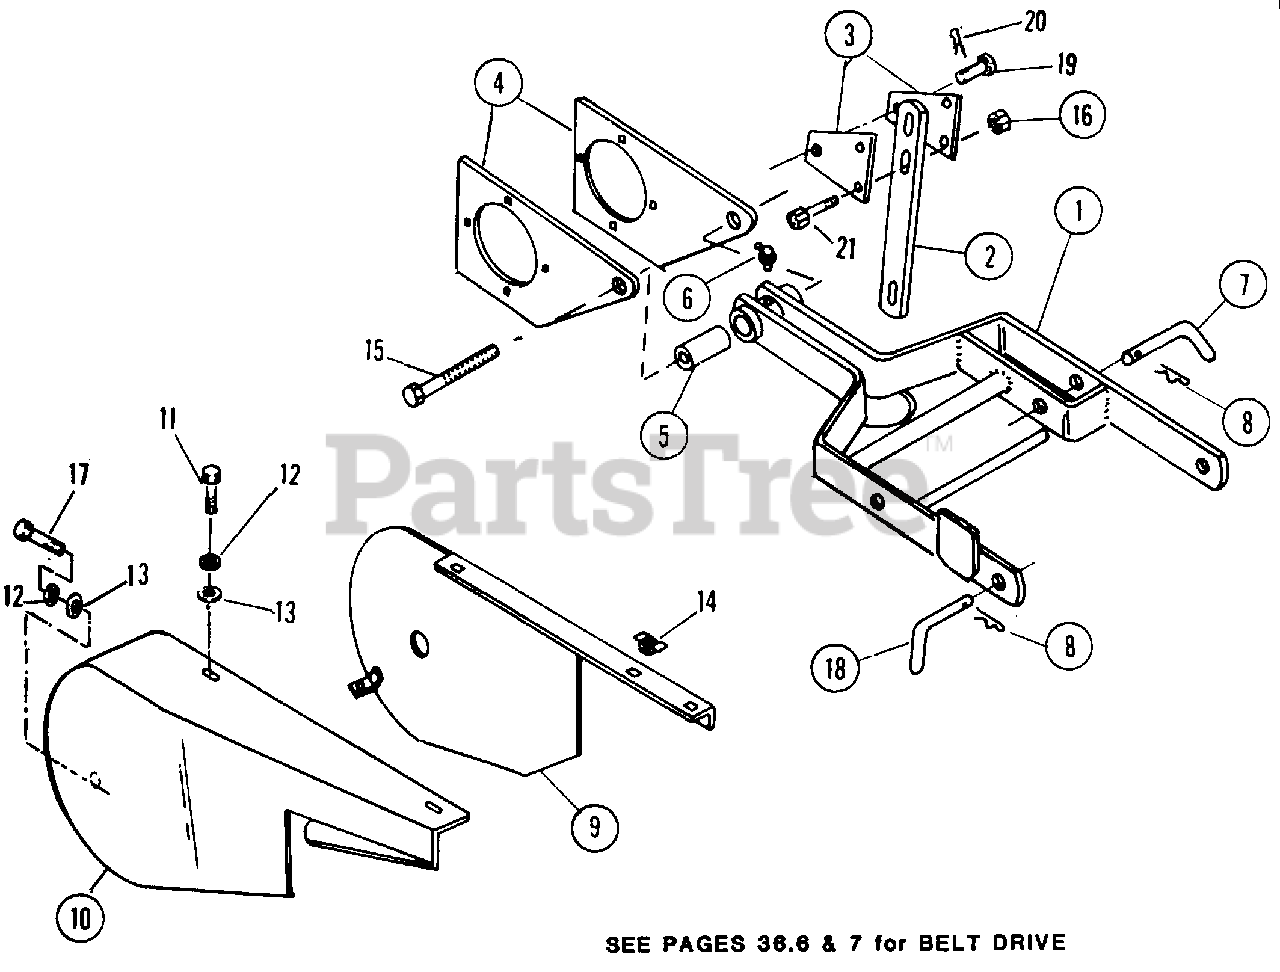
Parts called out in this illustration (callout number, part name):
1	LINK, LOWER LIFT
2	STRAP, BAR LIFT
3	PLATE, LIFT STRAP
4	PLATE, ATTACHING
5	BEARING, TUBE
6	FITTING, LUBE 1.187" Tall, 65°, for .4" Hole
7	L-PIN, LONG
8	PIN, COTTER HAIR 5/32 x l-13/16
9	SHIELD, BELT INNER
10	SHIELD, BELT OUTER
11	BOLT, 5/16 x 3/4 HEX HEAD
12	LOCKWASHER, 5/16
13	WASHER, 5/16 PLAIN
14	NUT, PUSH ON, 5/16-18 YZ
15	(NLA) BOLT,1/2C X1-1/4 GR5
16	LOCKNUT, 1/2 HEX
17	BOLT, 5/16 x 1/2 HEX HEAD
18	L-PIN, SHORT
19	PIN, DRILLED
20	PIN, Hair 1-3/16 x .156 dia.
21	BOLT, 3/8 x 1-1/4 BOLT
